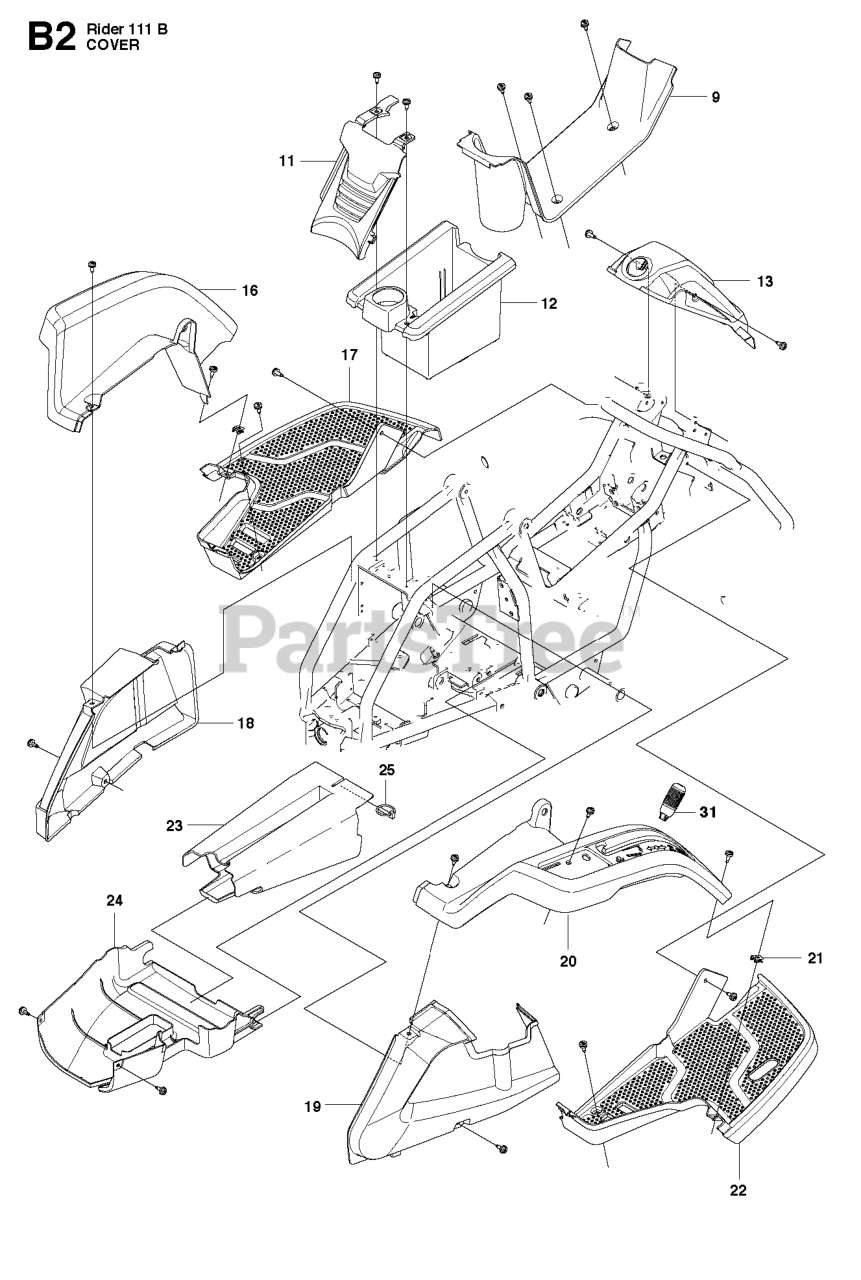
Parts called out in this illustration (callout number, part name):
12	BATTERY BOX
17	FOOT PLATE
20	CONTROL PANEL
22	FOOT PLATE
31	GEAR STICK KNOB
